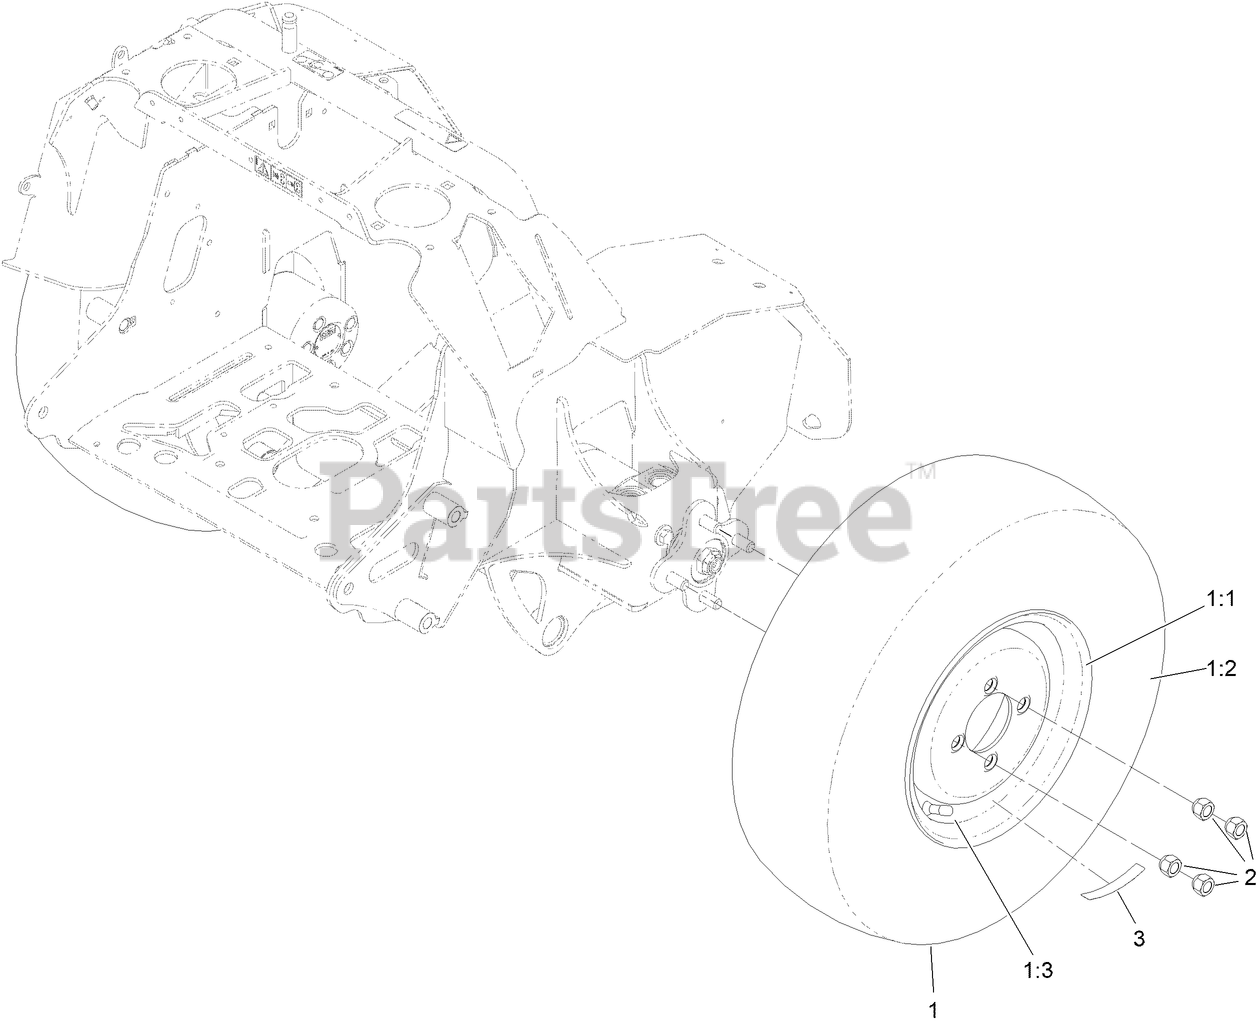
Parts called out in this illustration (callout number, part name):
1	WHEEL AND TIRE ASM
1:1	WHEEL 10 X 6
1:2	TIRE-21X8.5-10
2	NUT-LUG
3	DECAL-TORQUE WHEEL LUG-HUB
